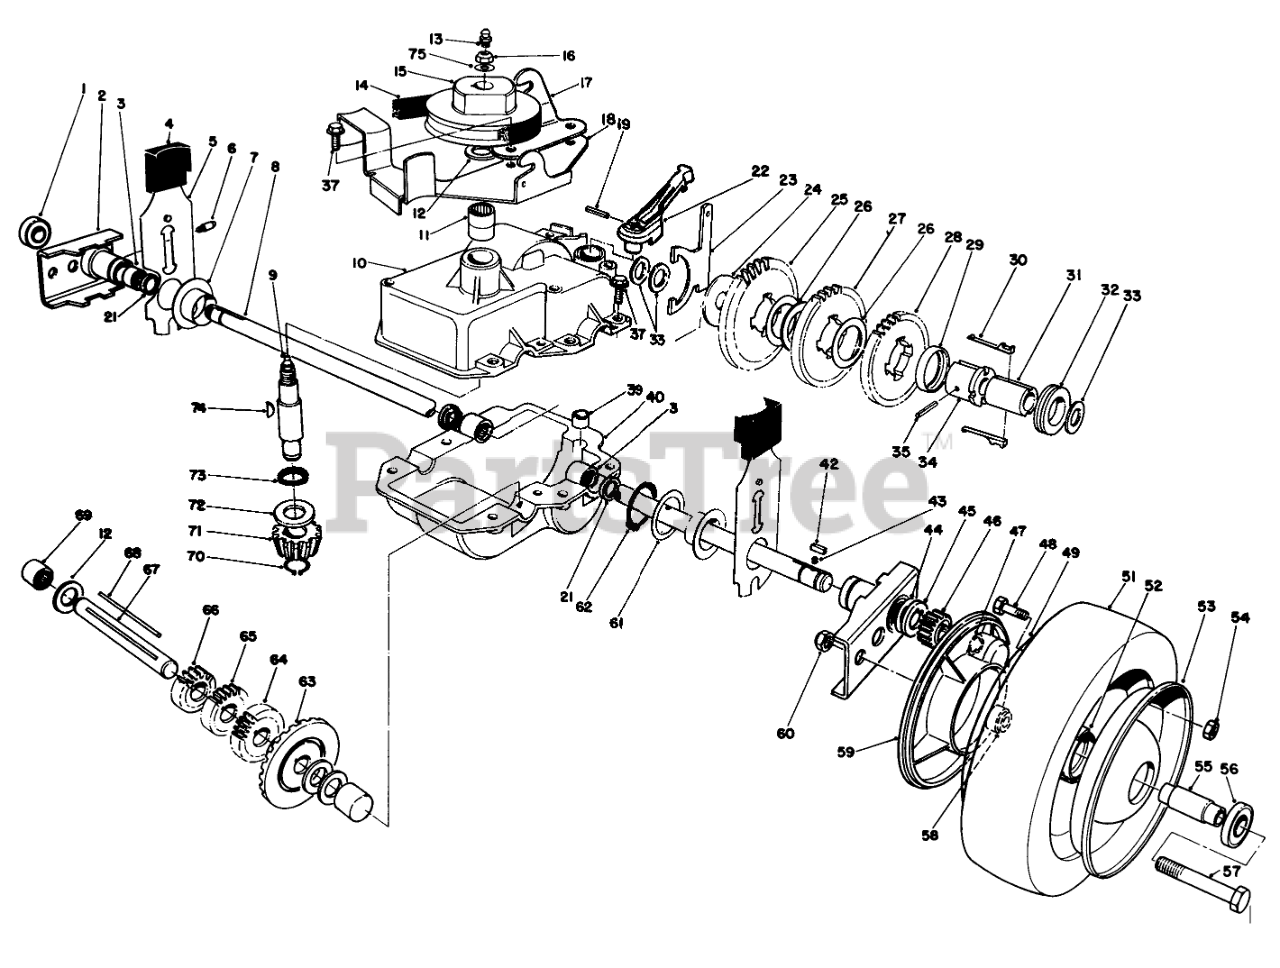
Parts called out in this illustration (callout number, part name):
1	BEARING-WHEEL
2	Pivot Arm Assembly (Incl. Ref. #1, 3, 6 & 21)
3	BEARING-ROLLER
4	KNOB-ARM
5	REAR SPRING ARM ASM
6	FITTING-GREASE
7	CAP-END
8	SHAFT-OUTPUT
9	Shaft-Input (Incl Ref. #13)
10	Upper Case Assembly (Incl. Ref. #11 & 73)
11	BEARING-NEEDLE
12	WASHER-THRUST
13	FITTING-GREASE, ZERK
14	V-BELT
15	PULLEY
16	NUT-HEX
17	Bracket-Traction Engage
18	Belt Guide Bracket
19	PIN-COIL
21	SEAL-OIL
22	LEVER-SHIFT
23	YOKE-SHIFT
24	WASHER
26	WASHER
27	GEAR-42T
28	GEAR-38T
29	RETAINER-KEY
30	KEY-SHIFT
31	SLEEVE
32	COLLAR-SHIFT
33	WASHER-PLAIN
34	SLEEVE-GEAR
35	PIN-GROOVE
37	SCREW-HWHTF
39	BUSHING-YOKE
40	CASE-GEAR, LOWER
42	KEY RECTANGULAR
43	SPRING-COMPRESSION
44	WASHER-THRUST, OUTER
45	WASHER-THRUST, OUTER
46	GEAR-PINION
47	RING-RETAINING
48	SCREW-HH
49	Wheel-Half
52	HUB-BEARING
53	Wheel-Half
54	NUT-LOCK, NI
55	SPACER-BEARING
56	BEARING-WHEEL
57	SCREW-HH
58	SPACER-COVER, WHEEL
59	COVER-WHEEL
60	NUT-LOCK, CONE
61	WASHER
62	RING-RETAINING
63	GEAR-BEVEL
64	GEAR-18T
65	GEAR-14T
66	GEAR-12T
67	SHAFT-INTERMEDIATE
69	BEARING-NEEDLE, CLOSED
70	RING-RETAINING
71	PINION-BEVEL
72	WASHER-THRUST
74	KEY-WOODRUFF
75	WASHER-FLAT
